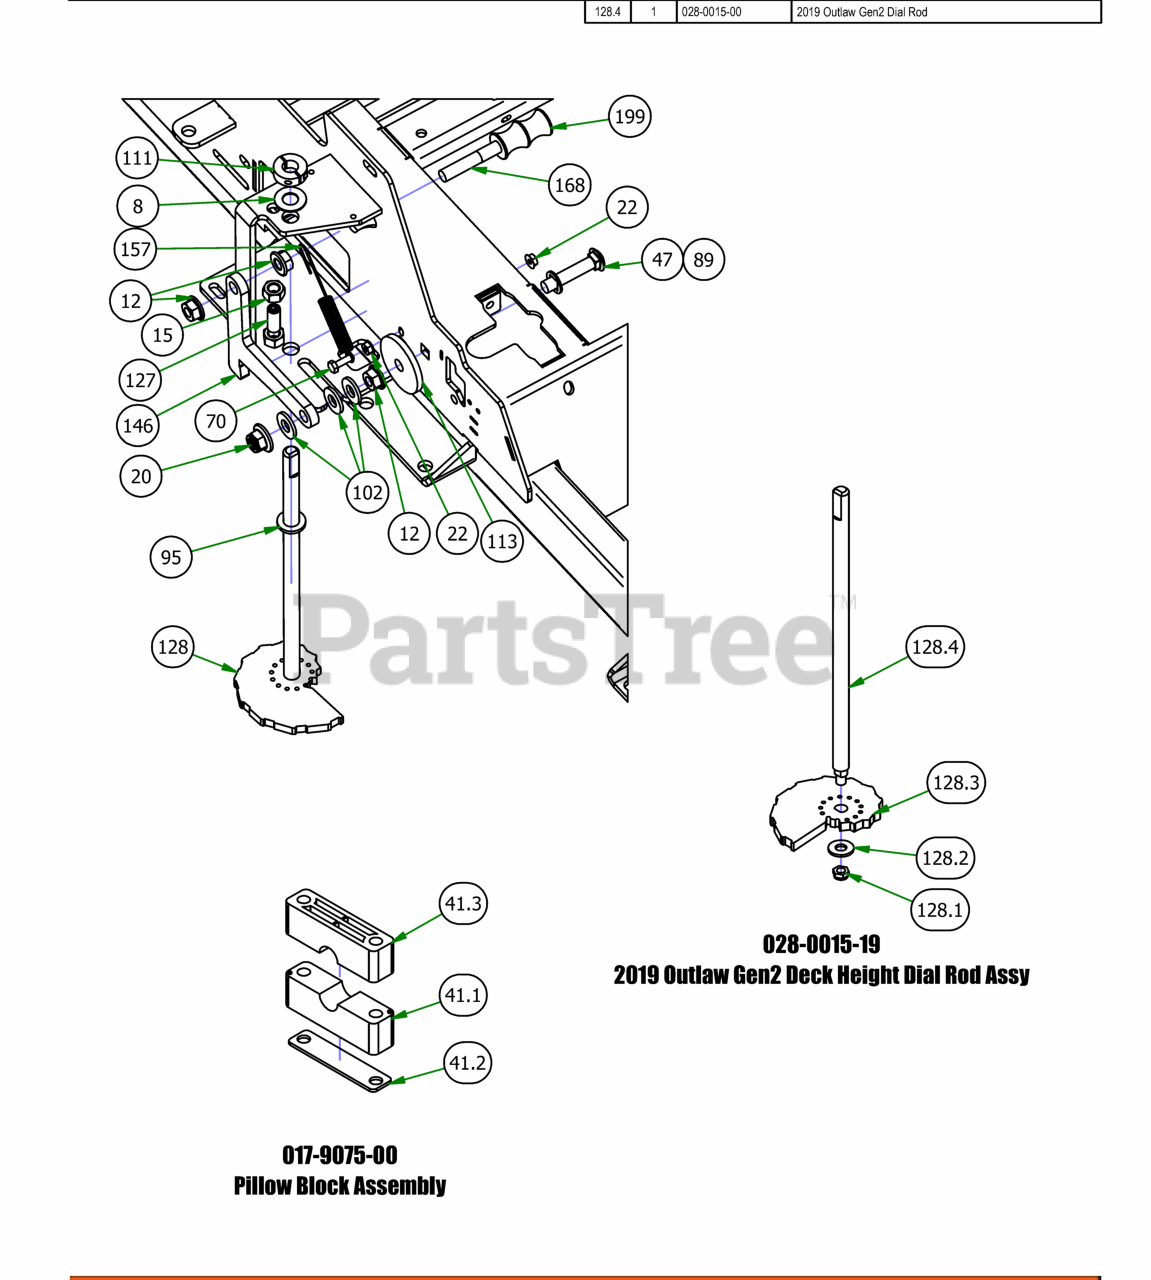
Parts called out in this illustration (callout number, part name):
8	.625 ID x 1.250 OD x .062 THK F/W Nylon
12	1/2" Flange Nut
15	1/2" Hex Nut
20	1/2-13 NYLON INSERT FLANGE LOCKNUT ZINC
22	1/4-20 Hex Flange Nuts Zinc w/Serrations
41.1	Two Piece Pillow Block (Male)
41.2	Two Piece Pillow Block Strap
41.3	Two Piece Pillow Block (Female)
47	1/2 x 2-1/2 Carriage Bolt
70	1/4-20 x 1-1/4 GR 5 Hex Bolt
89	.517 Square Hole Round Washer
95	.635 ID X 1.120 OD X .140 THICK FLAT WASHER NYLON
102	.505 Nylon Spacer
111	5/8" Split Collar
113	MZ Deck Idler Spacer
127	Dial Rod Plunger
128	2019 Outlaw Gen2 Deck Height Dial Rod Assy
128.1	3/8-24 Nylon Insert jam locknut
128.2	3/8" Flat Washer
128.3	2019 Deck Height Cam
128.4	2019 Outlaw Gen2 Dial Rod
146	2019 Outlaw Deck Travel Lock
157	Brake Spring
168	Seat Bracket Pin
199	Travel Lock Rubber Grip
